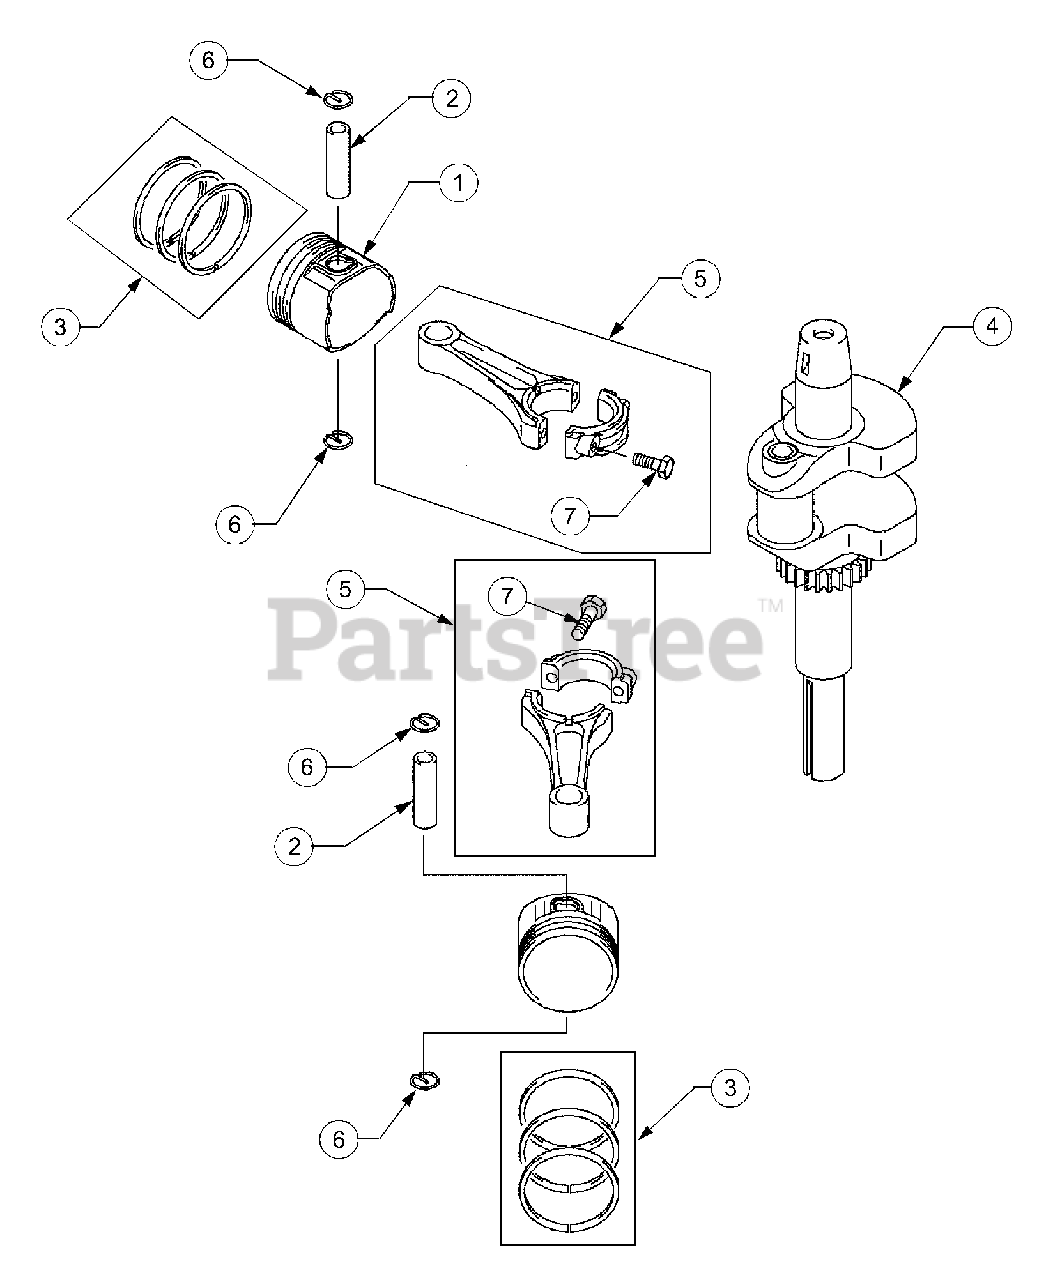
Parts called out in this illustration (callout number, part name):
1	Piston, Engine
3	Ring Set, Piston
4	Crankshaft, Comp
5	Rod Assy, Connecting
7	Bolt, Flanged
